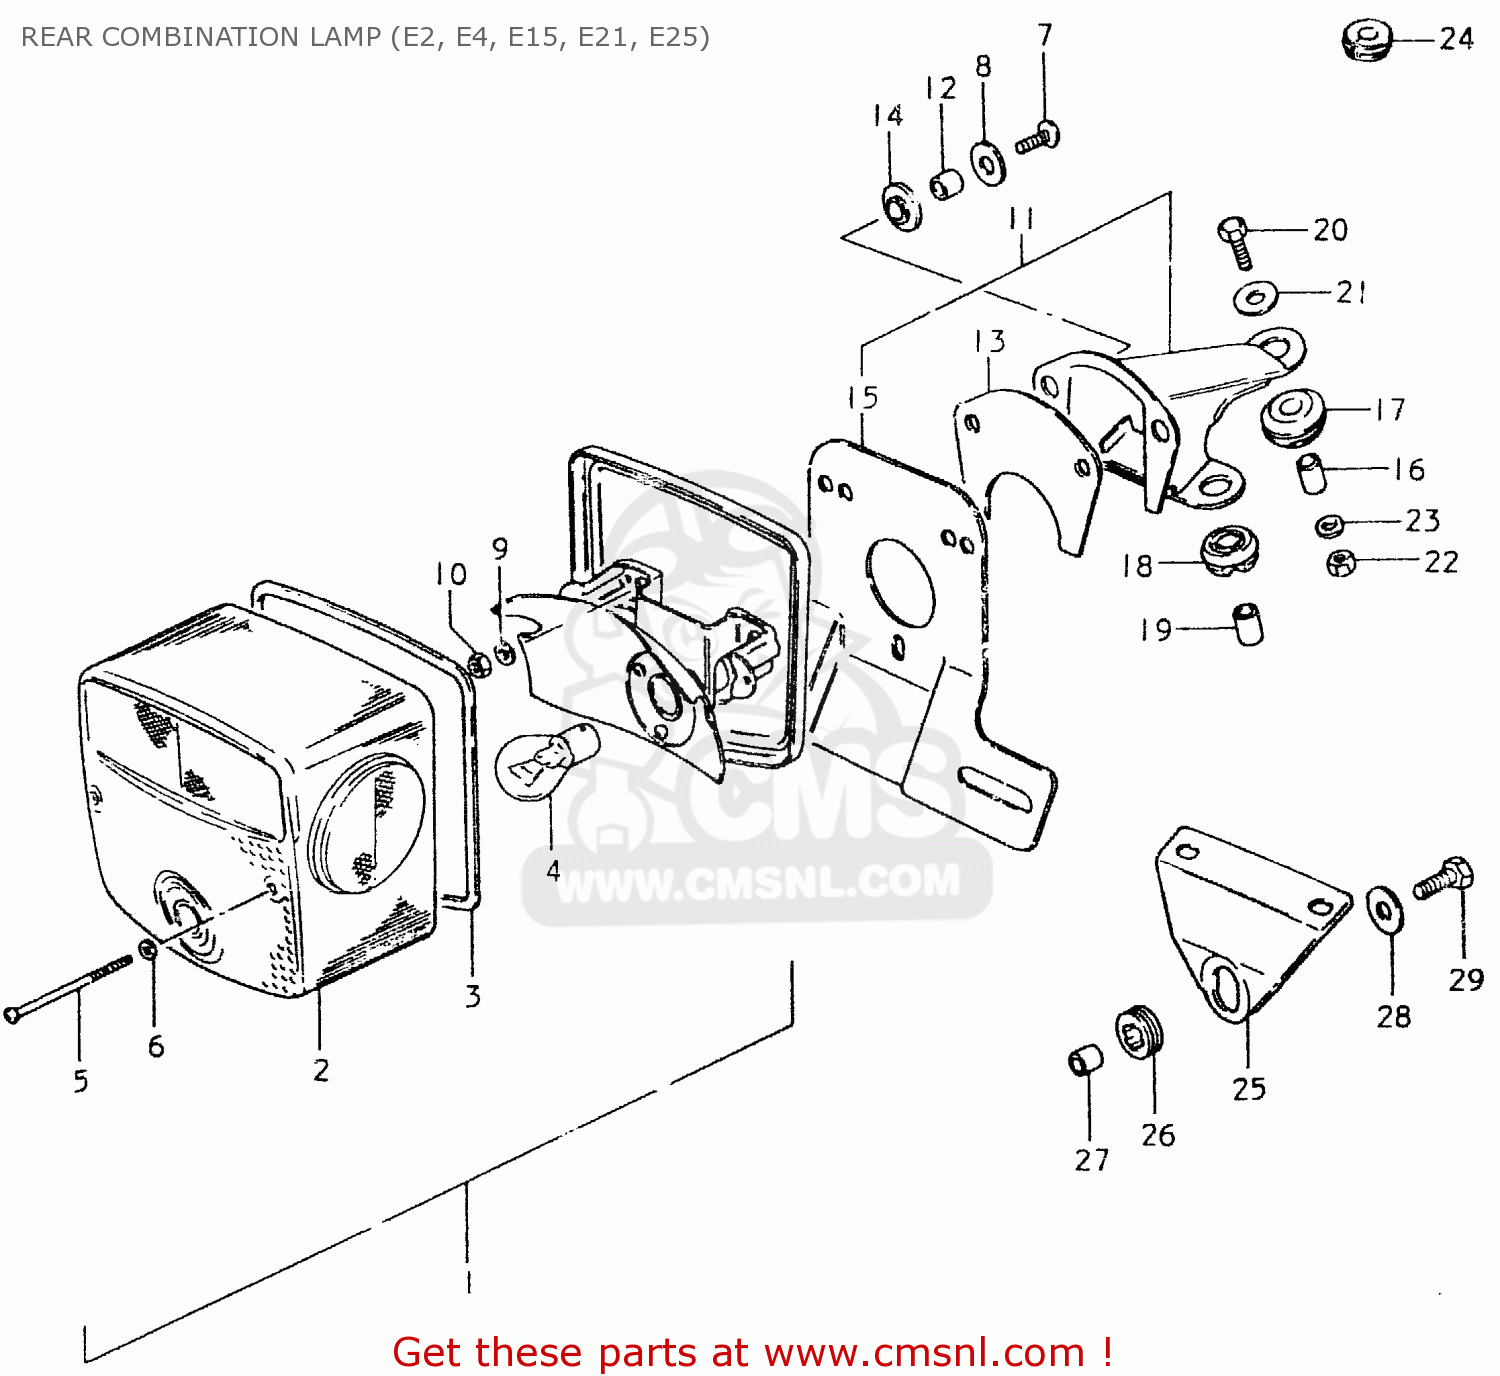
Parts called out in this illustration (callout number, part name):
1	LAMP UNIT, TAIL
2	LENS
3	GASKET (NAS)
4	BULB (6V,21/5W)
5	SCREW (4X55)
6	GASKET (NAS)
7	TAPPING SCREW
8	WASHER,REAR COMBINATION LAMP
9	NUT
10	LOCK WASHER
11	BRACKET SET
12	SPACER
13	CUSHION
14	CUSHION,REAR COMBINATION LAMP
15	PLATE, LICENCE
16	SPACER
17	CUSHION,REAR COMBINATION LAMP
18	CUSHION,REAR COMBINATION LAMP
19	SPACER
20	BOLT
21	WASHER (6.5X20X1.2)
22	NUT
23	WASHER 6MM
24	GROMMET
25	REINFORCEMENT
26	CUSHION
27	SPACER (6.1X9X9)
28	WASHER (6.5X20X1.2)
29	BOLT, UPPER
